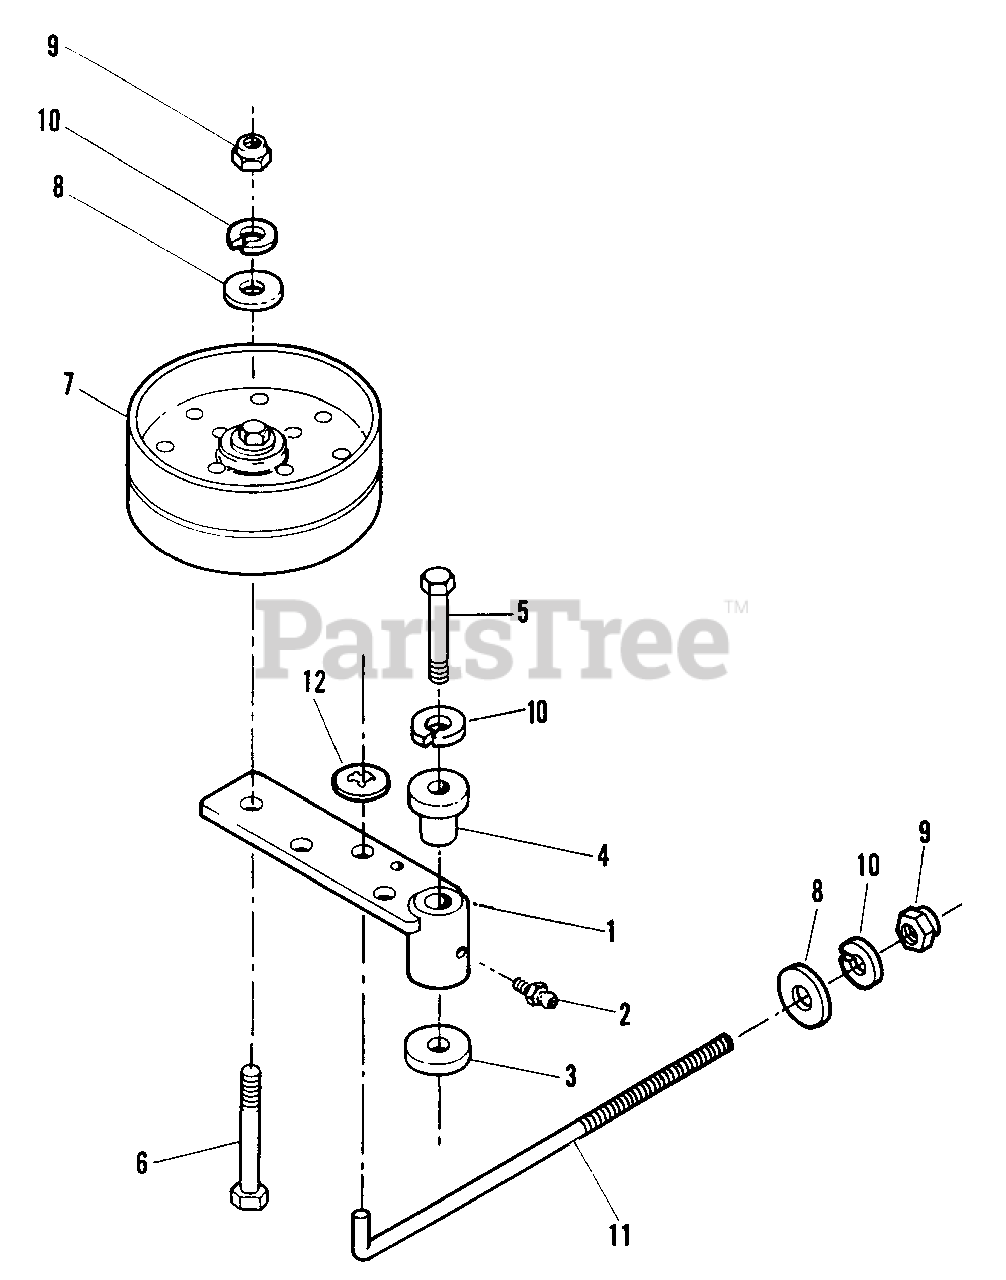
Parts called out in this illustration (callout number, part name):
1	WELDMENT, 48" Blade/Blade Idler
2	FITTING, 1/4"-28 Straight Zerk Grease
3	MACHINE BUSHING, 14 Ga. 1"
4	SPACER, Pivot
5	SCREW, 3/8C x 3" Grade 5 Hex Cap
6	SCREW, 3/8C x 1-3/4" Grade & Hex Cap
7	PULLEY, Idler 5.0
8	WASHER, 3/8" Flat
9	NUT, 3/8" C Nyloc
10	WASHER, 3/8" Split Lock
11	ROD, 10-1/2"
12	RETAINER, 3/8"
